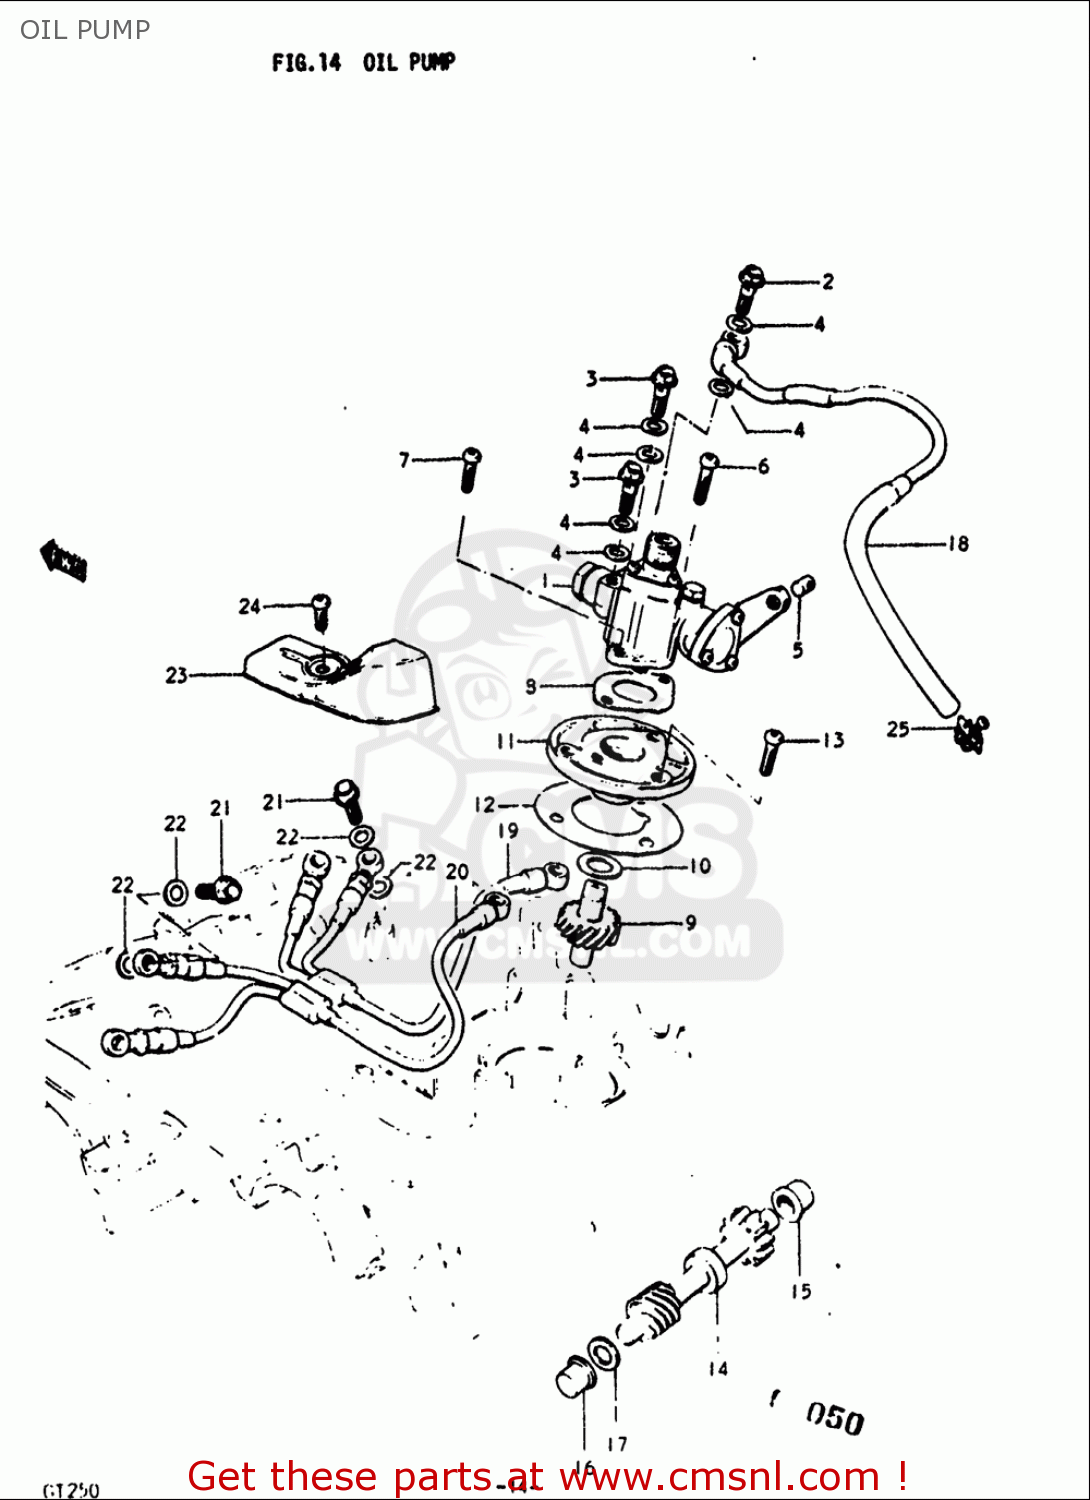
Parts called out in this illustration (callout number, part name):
2	UNION BOLT
3	UNION
4	GASKET(6.2X11X1).2 (NAS)
5	TERMINAL, CABLE
6	SCREW
7	SCREW
10	SHIM(10X20X1)
12	GASKET,OIL PUMP GEAR CASE (MCA)
13	SCREW
17	SHIM(10X16X1)
21	UNION BOLT
22	GASKET(6.2X11X1).2 (NAS)
24	SCREW
25	CLAMP
